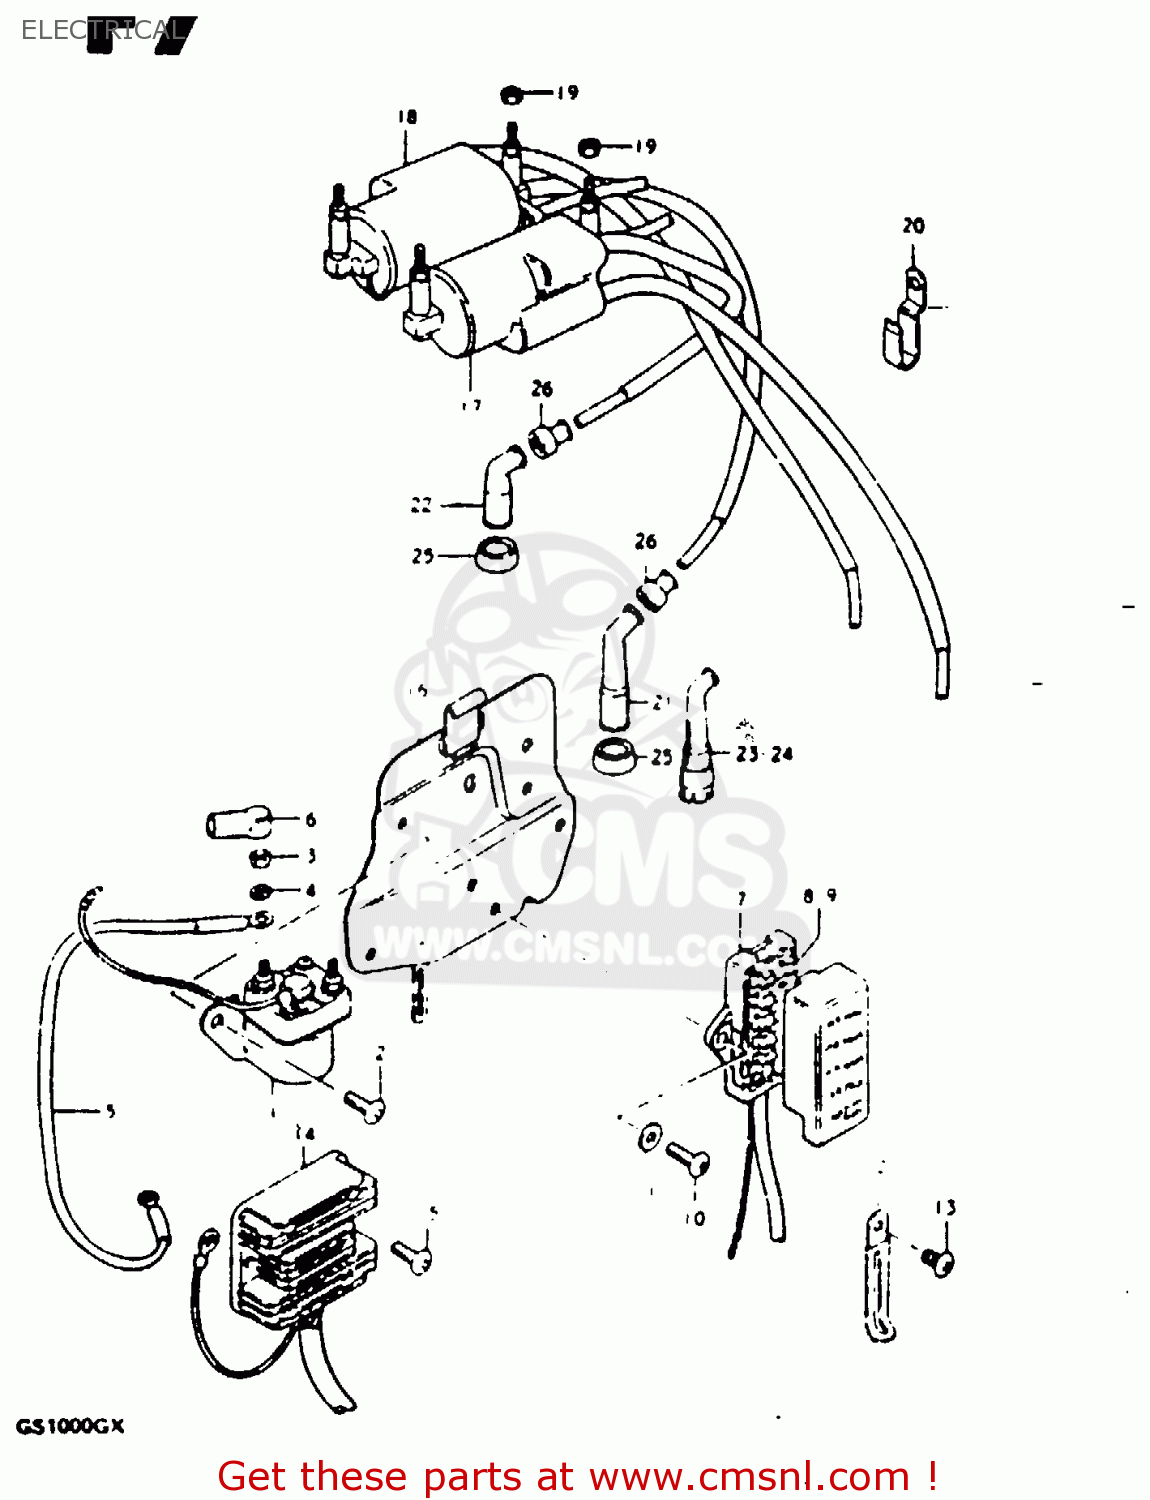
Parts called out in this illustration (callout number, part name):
1	RELAY ASSY,STARTING MOTOR
2	SCREW
3	NUT 6MM
4	LOCK WASHER
5	WIRE,STARTER MOTOR LEAD
6	CAP,STARTER RELAY
7	BOX ASSEMBLY,FUSE
8	FUSE(10A)
9	FUSE(15A)
10	SCREW 6X12
11	WASHER
12	CLAMP L:35
13	SCREW
14	RECTIFIER ASSEMBLY
15	SCREW 6X12
16	HOLDER COMP,ELECTRONIC PARTS
17	COIL ASSEMBLY,IGNITION
18	COIL ASSEMBLY,IGNITION
19	NUT
20	CLAMP
23	CAP,SPARK PLUG
24	CAP, SPARK PLUG (S)
25	SEAL,SPARK PLUG
26	SEAL,SPARK PLU
